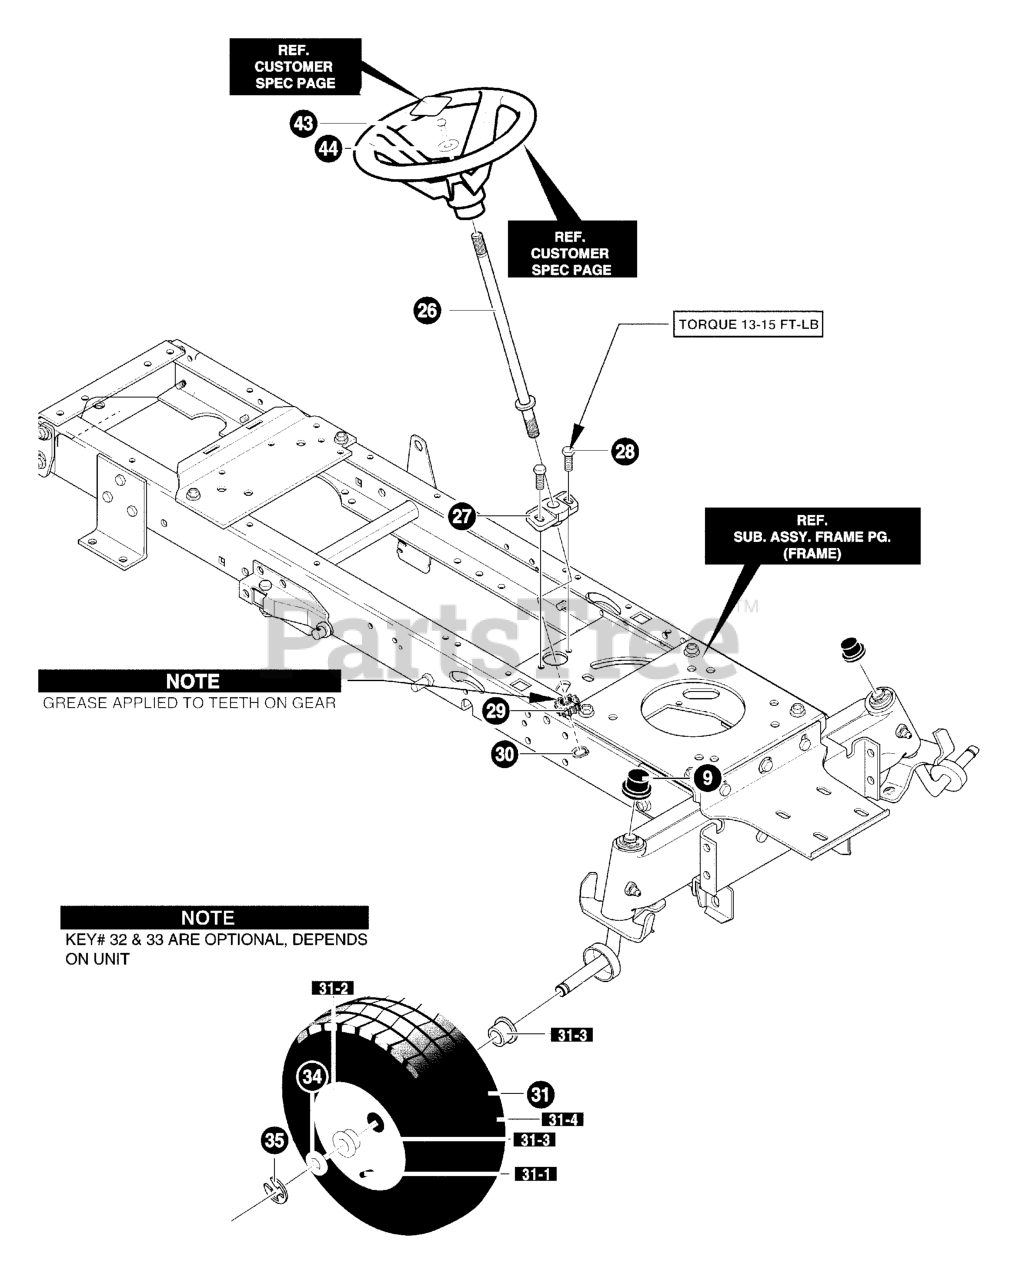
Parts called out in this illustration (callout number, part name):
9	DUST HUB CAP
26	SHAFT, STEERING BOLT ON
27	BEARING-LOWER
28	SCREW, 5/16-18 x 0.75
29	GEAR PINNION
30	RING, RET E.
31	TIRE & RIM 15X6.00-6
31-1	VALVE STEM
31-3	BEARING
31-4	TIRE 15X6.00-6
34	WASHER, FLAT
43	SCREW, 1/4-20X.75
44	FLATWASHER
